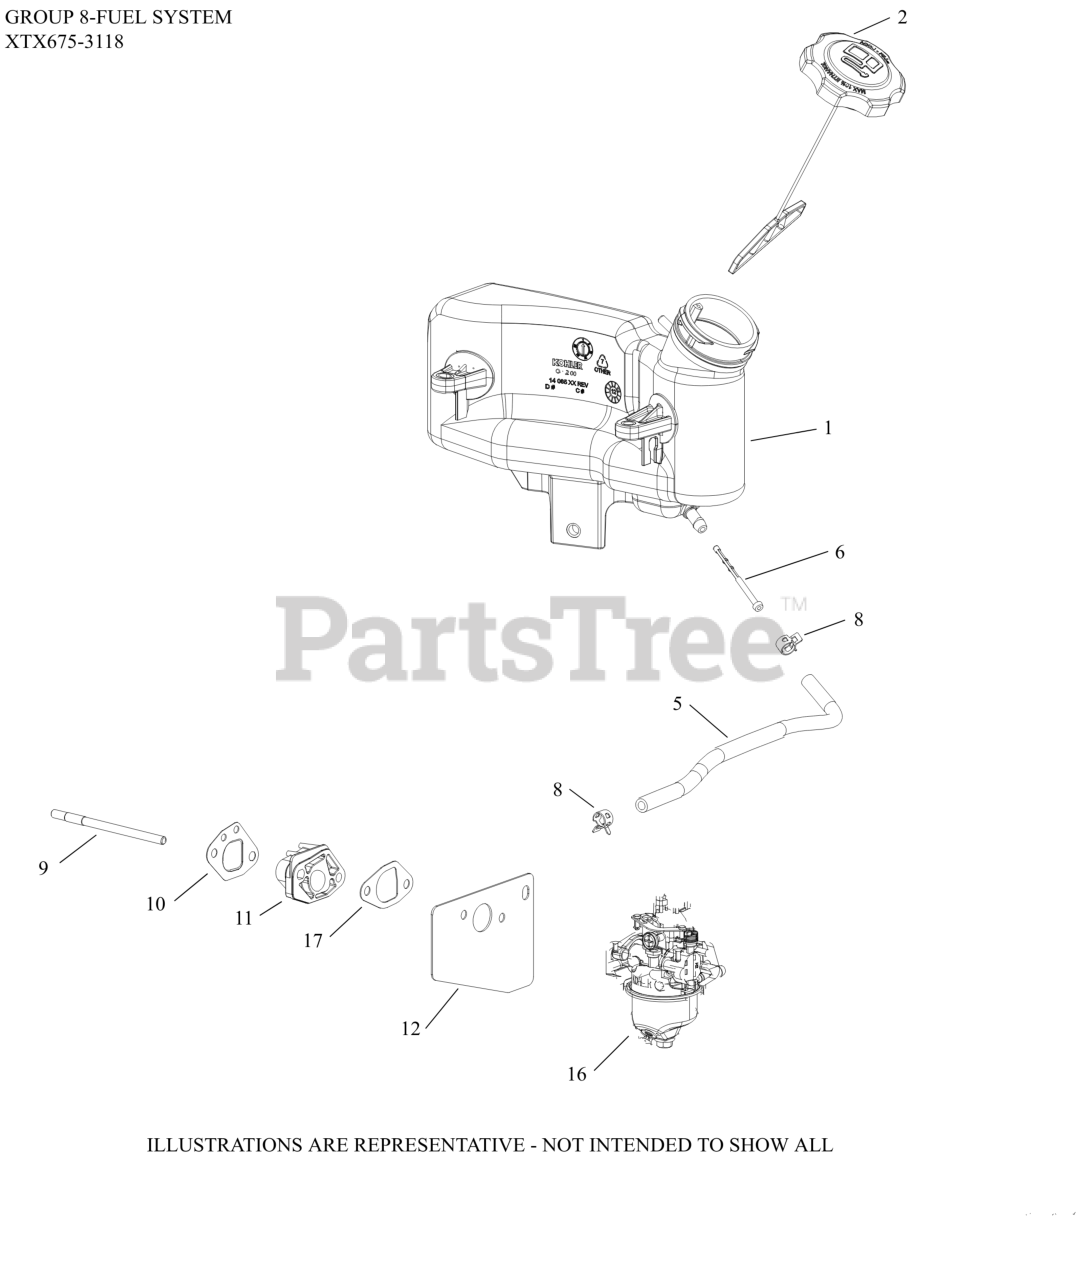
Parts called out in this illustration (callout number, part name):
1	TANK, FUEL
2	FUEL CAP ASSEMBLY
5	HOSE, FUEL LOW-PERMEATION (CKY)
6	FILTER, FUEL IN-NIPPLE
8	CLAMP, HOSE (NON-CALIF)(#1423710S)
9	STUD,M6X1.0X100.2MM
10	GASKET, SPACER - USE 14 041 24-S
11	SPACER, CARBURETOR
12	KIT, CARBURETOR HEAT SHIELD GASKET
16	KIT, CARBURETOR COMPLETE
17	KIT, INTAKE GASKET
NI	KIT, HIGH ALTITUDE (4,000-8,000 FT)
NI	KIT, CARBURETOR REPAIR (RUIXING)
